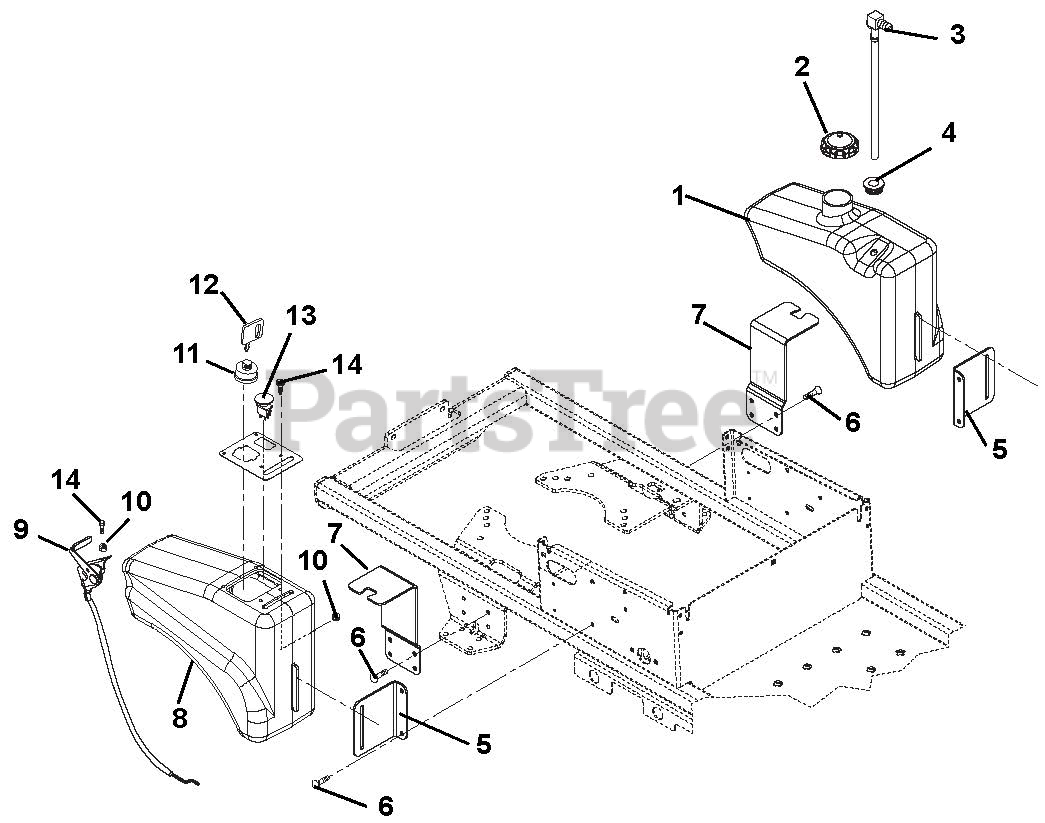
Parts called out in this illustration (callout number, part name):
1	LH FENDER/TANK
2	FUEL CAP
3	FITTING, TANK
4	BSHG-FLG .375 X 1.062 X .625 R
5	BKT,FUEL TANK
6	@SCR-TAP .31-18X.50 HWH TR YWZ
7	MOUNT,FUEL TANK
8	RH FENDER/TANK
9	CABLE,THROTTLE
10	@NUT-LK-NYL 10-24 W/INSRT YWZC
11	KEY SWITCH
12	KEY -W/CAP
13	SWITCH, CLUTCH
14	@SCR-MCH 10-24X.75 HWH YWZC
15	CONTROL PANEL
